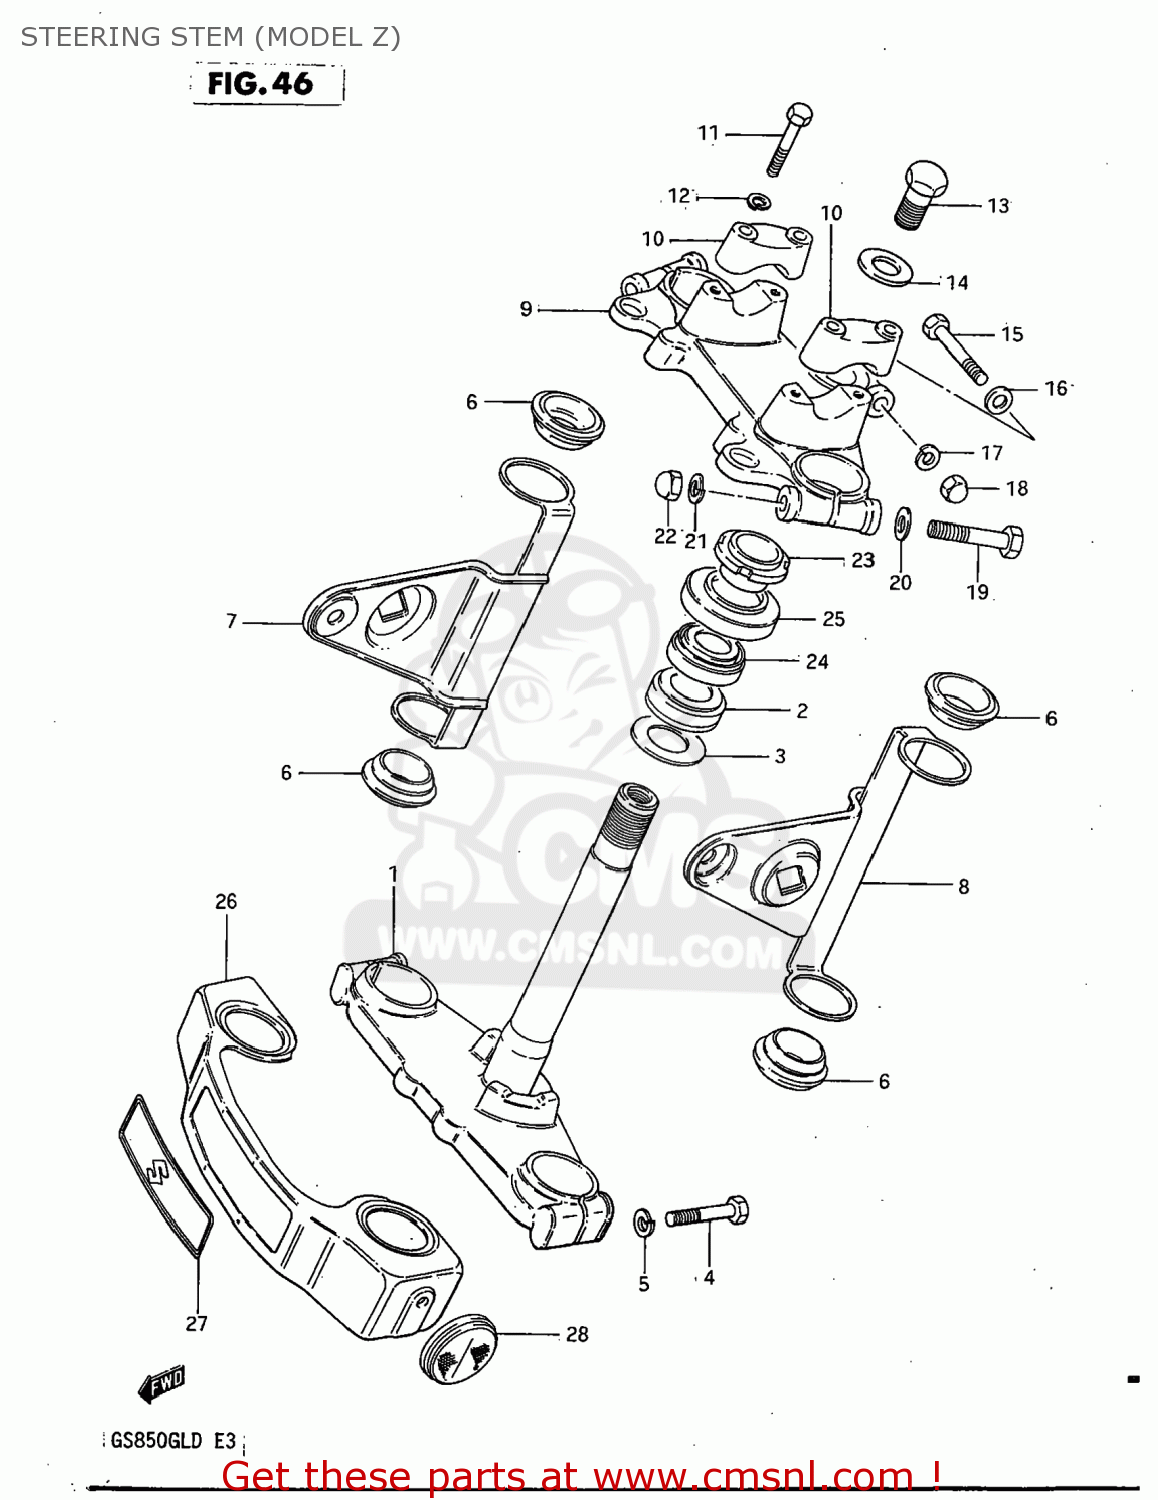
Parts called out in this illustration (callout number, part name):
1	STEM,STEERING
2	BEARING
3	WASHER,THRUST
4	BOLT
5	LOCK WASHER
6	CUSHION,HEADLAMP BRACKET
7	BRACKET,HEADLAMP,RIGHT
8	BRACKET,HEADLAMP,LEFT
9	HEAD,STEERING STEM
10	HOLDER,HANDLE(BLACK)
11	BOLT
12	LOCK WASHER
13	NUT,STEM HEAD
14	WASHER,STEERING STEM
15	BOLT 8X50
16	WASHER
17	WASHER,LOCK,8.
18	NUT
19	BOLT 10X55
20	WASHER
21	LOCK WASHER
22	NUT, LOWER LH
23	NUT,STEERING STEM
24	TAPER,ROLLER BEARING
25	DUST SEAL,STEERING,UPPER
26	COVER,FRONT FORK
27	EMBLEM,FR FORK COVER
28	REFLEX REFLECTOR,RR
